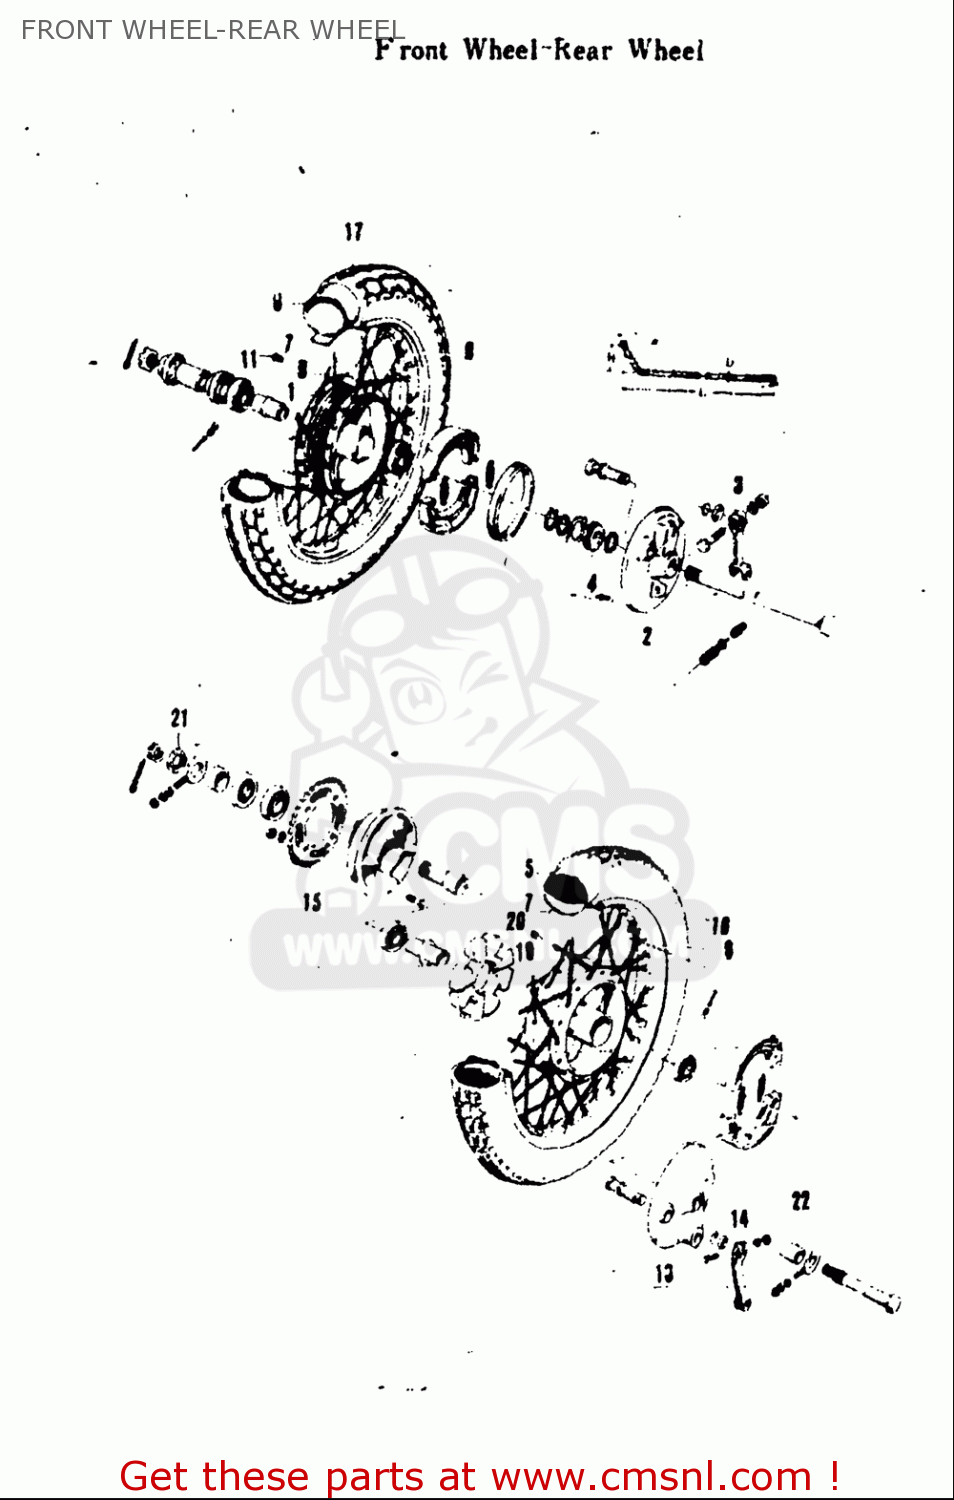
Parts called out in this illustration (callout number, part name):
3	LEVER,FR BRAKE CAM
7	SPOKE SET,FR
8	RIM,WHEEL(1.40X18)
14	LEVER,RR BRAKE CAM
15	SPROCKET,REAR
17	SPOKE SET,RR
21	NUT
